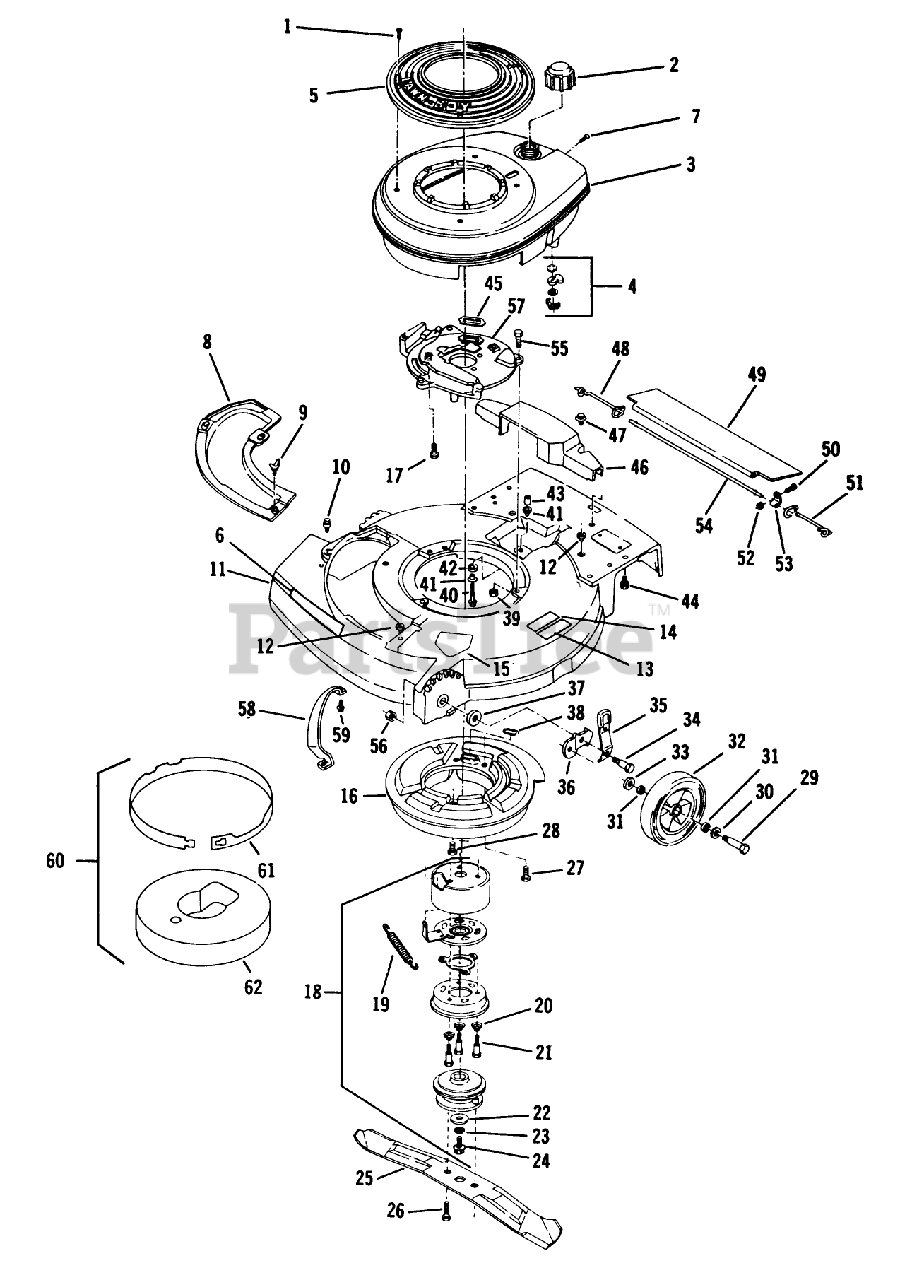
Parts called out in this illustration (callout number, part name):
1	SCREW - SELF TAPPING
2	FUEL CAP & INSERT
4	SHUT OFF VALVE KIT
7	SCREW S
9	WING SCREW LAWRE
13	PAD FOOT
17	SCREW V
19	SPRING
21	SCREW,SHOULDER SM
22	WASHER
26	SCREW SEMS
28	SCREW
29	BOLT WHEEL
30	SPACER
31	WASHER
32	WHEEL & TIRE KIT
33	WASHER WROUGHT
34	BOLT
37	WASHER
38	SEAL
39	NUT-LOCK F
41	SPACER ECK PRES
42	GROMMET
43	SPACER
44	SCREW
47	SCREW SEMS TRM HEX HD
48	SPRING;TRAILING SHIELD RH
49	SHIELD
51	SPRIG T/SHLD ASOC
52	LOCKNUT E
53	CLAMP ROD KMC
54	ROD 21" ADVANCE
55	SCREW-HH
56	LOCKNUT
58	BAR-TOE
